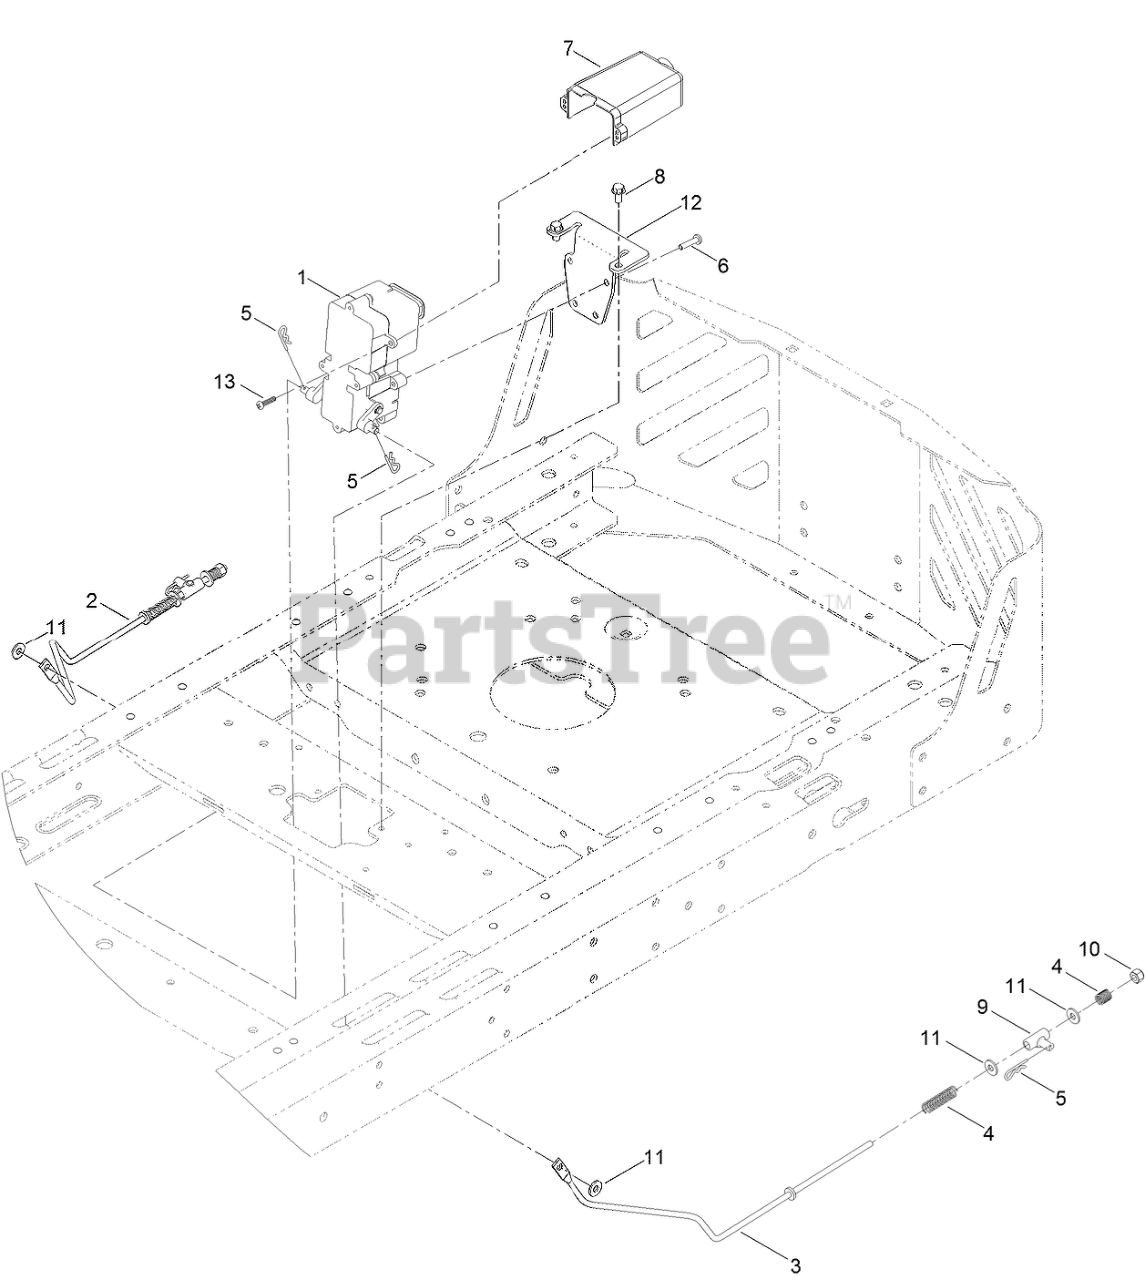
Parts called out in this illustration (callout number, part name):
1	BRAKE BOX ASM
2	ROD-BRAKE, RH
3	ROD-BRAKE, LH
4	SPRING-COMPRESSION
5	PIN-COTTER
6	SCREW-PPH
7	COVER-CONNECTOR
8	SCREW-HWH
9	MOUNT-PIVOT
10	NUT-LOCK, NI
11	WASHER
12	BRACKET-MOUNT, BRAKE
13	SCREW-PPH
